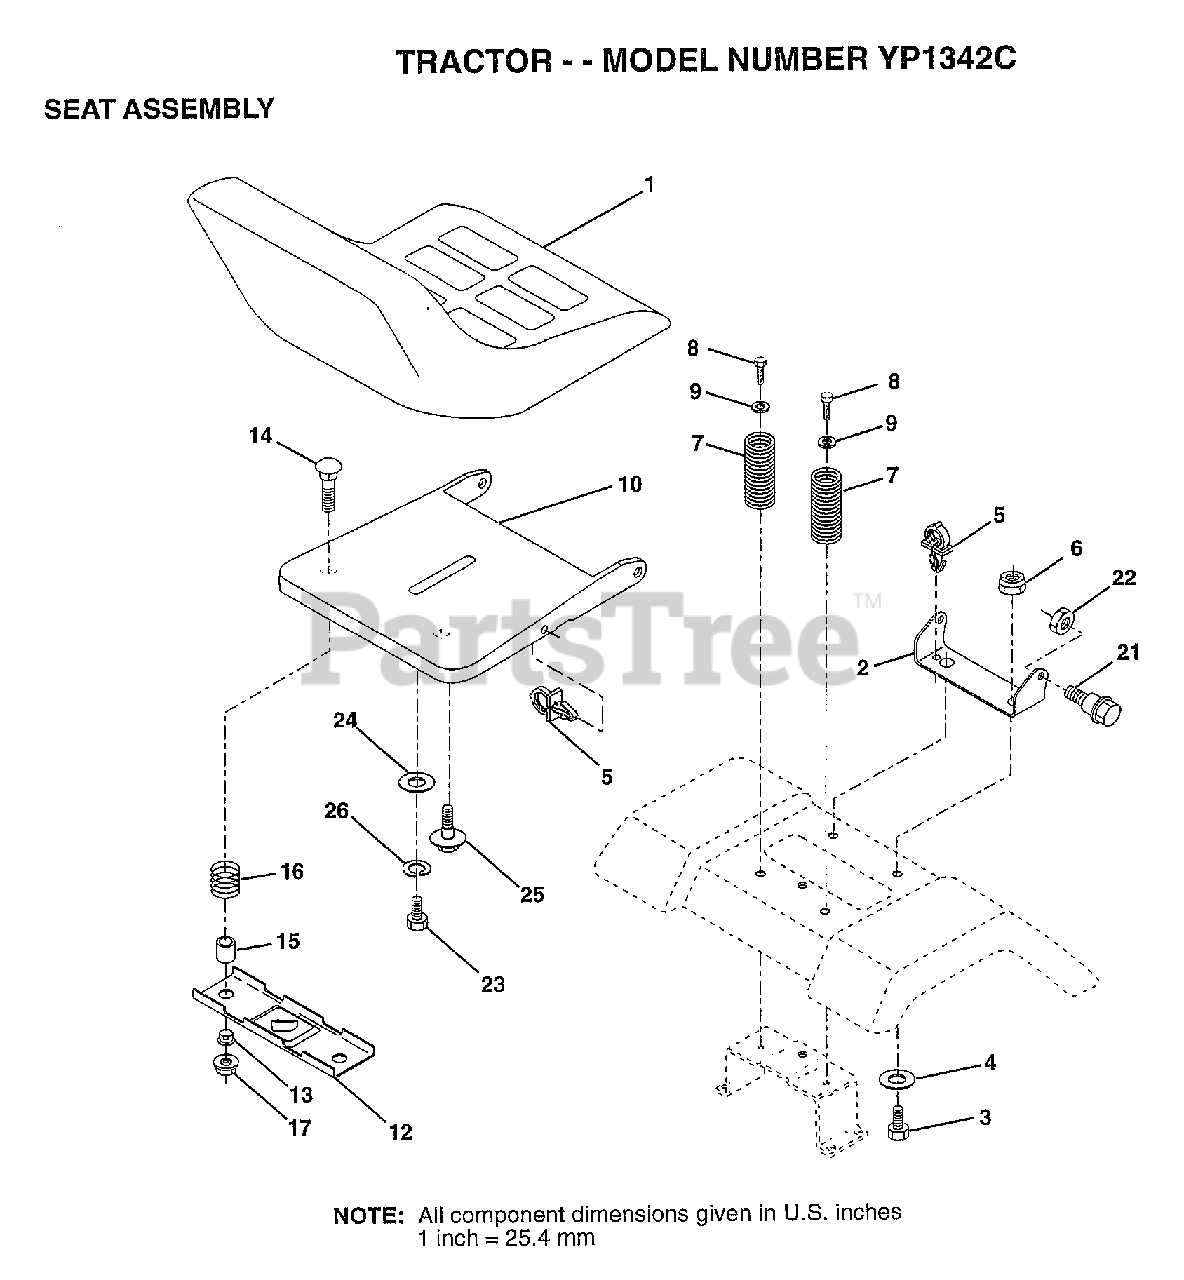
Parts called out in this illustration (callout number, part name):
1	SEAT
2	BRACKET PVT SEAT
3	BOLT
4	WASHER PM
5	CLIP.PUSH-IN.HING
6	NUT
7	SPRING COMPRESSIO
8	SCREW GTV
9	WASHER
10	PAN-SEAT
12	BRKT SWITCH
13	BUSHING
14	BOLT-RD HD SQ NK
15	SPLIT SPACER
16	SPRING
21	"BOLT,SHOULDER"
22	NUT
23	BOLT
24	WASHER
25	"BOLT,SHOULDER"
26	LOCKWASHER
